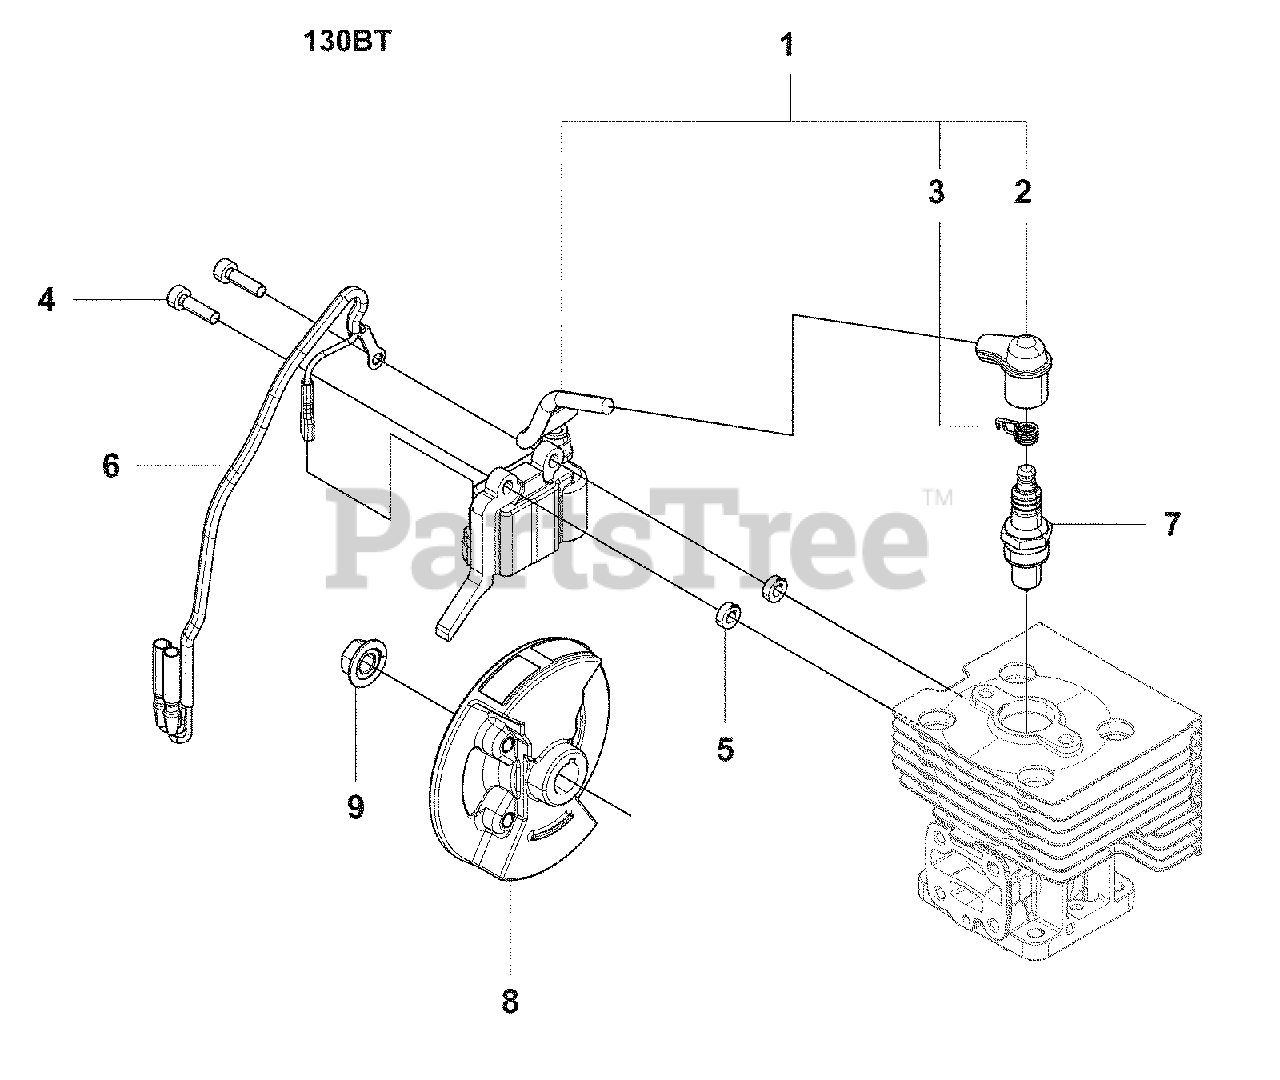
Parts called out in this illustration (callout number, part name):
1	Ignition Coil, A
2	Cap
3	Spring
4	Torx Bolt, M4 X L16
6	CORD-COMPL.
7	Spark Plug, CMR7H BLYB
9	Nut
